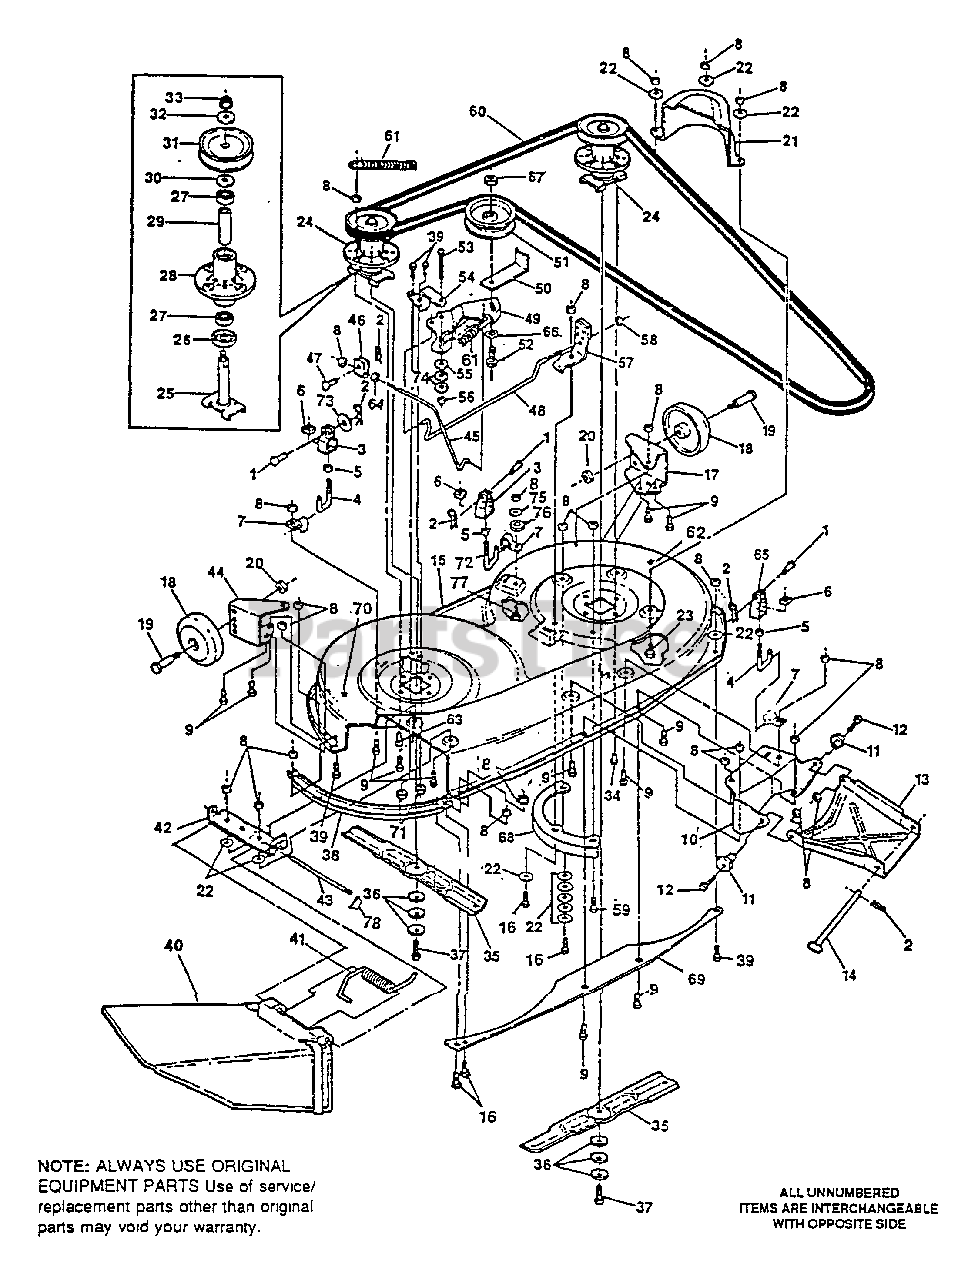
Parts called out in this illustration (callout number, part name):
1	Pin, Clevis
2	Hairpin, Cotter
4	Lift Rod
5	Nut, Hx Jam 1/2-13 Thd.
6	Nut, Sq. 1/2-13 Thd.
8	Nut, Hx, Lock 5/16-18 Thd.
9	Screw, Hx Hd, 5/16-18 x 1 In.
10	Bracket, Front
11	Nut, Adjusting
12	Screw, Hx Hd. 5/16-18 x 1 In.
13	Channel, Draw Bar
14	Rod, Drawbar
15	Mower Deck
16	Screw, Hx, 5/16-18 x 3/4 in.
17	Wheel Bracket, L.H.
19	Shoulder Bolt, 3/8-16 Thd.
20	Nut, Hex, Ctrlk, 3/8-16 Thd.
21	Belt Cover, Left Pulley
22	Flatwasher, 11/32 In.
23	Screw, Hx Hd, 5/16-18 x 5/8 In.
24	Quill Assembly
25	Saddle & Shaft Assembly
26	Dust Shield
27	Bearing
28	Quill Housing
29	Spacer Tube
33	Nut, Wd Fl, Lk 7/16-20 Thd.
34	Screw, Wshr Hd, 5/16-18 x 7/8"
36	Washer, Spring
37	Screw, Hx Hd, 3/8-24 x 1 In.
38	Toe Guard
39	Screw, Hx Hd, 5/16-18 x 3/4 In.
40	Chute Deflector
42	Bracket, Chute Mount
43	Rod, Chute
44	Wheel Bracket, R.H.
45	Clutch Rod
46	Clevis, Clutch
47	Pin, Clevis
48	Rod, Brake
49	Idler Assembly
49	Idler Arm
49	Brake Pad
50	Belt Retainer
51	Idler Pulley
52	Carriage Bolt, 3/8-16 x 2 In.
53	Shoulder Bolt, 3/8-16 x 3/4 In.
54	Idler Brace
55	Washer, Flat
56	Nut, Hx, Wd Fl, 3/8-16 Thd.
57	Blade/Brake Assembly
58	Nut, Hx, Ctrlk, 1/4-20 Thd.
59	Screw, Hx, 5/16-18 x 1-1/4 In.
60	Belt, 82 In. Long
62	Decal, No Step
63	Screw, Tap, 5/16-18 x 1-3/8 In.
64	Nut, Hx, 5/16-18 Thd.
66	Washer, Split, Lock 3/8 In.
67	Nut, Hx, 3/8-16 Thd.
68	Baffle, Deck
69	Baffle, Deck Front
70	Decal, Danger
71	Nut, 5/16-18 Thd.
72	Lift Rod
73	Washer, Flat
74	Washer, Flat
75	Washer, Flat
77	Screw, 5/16-18 x 1 In.
78	Push Nut
